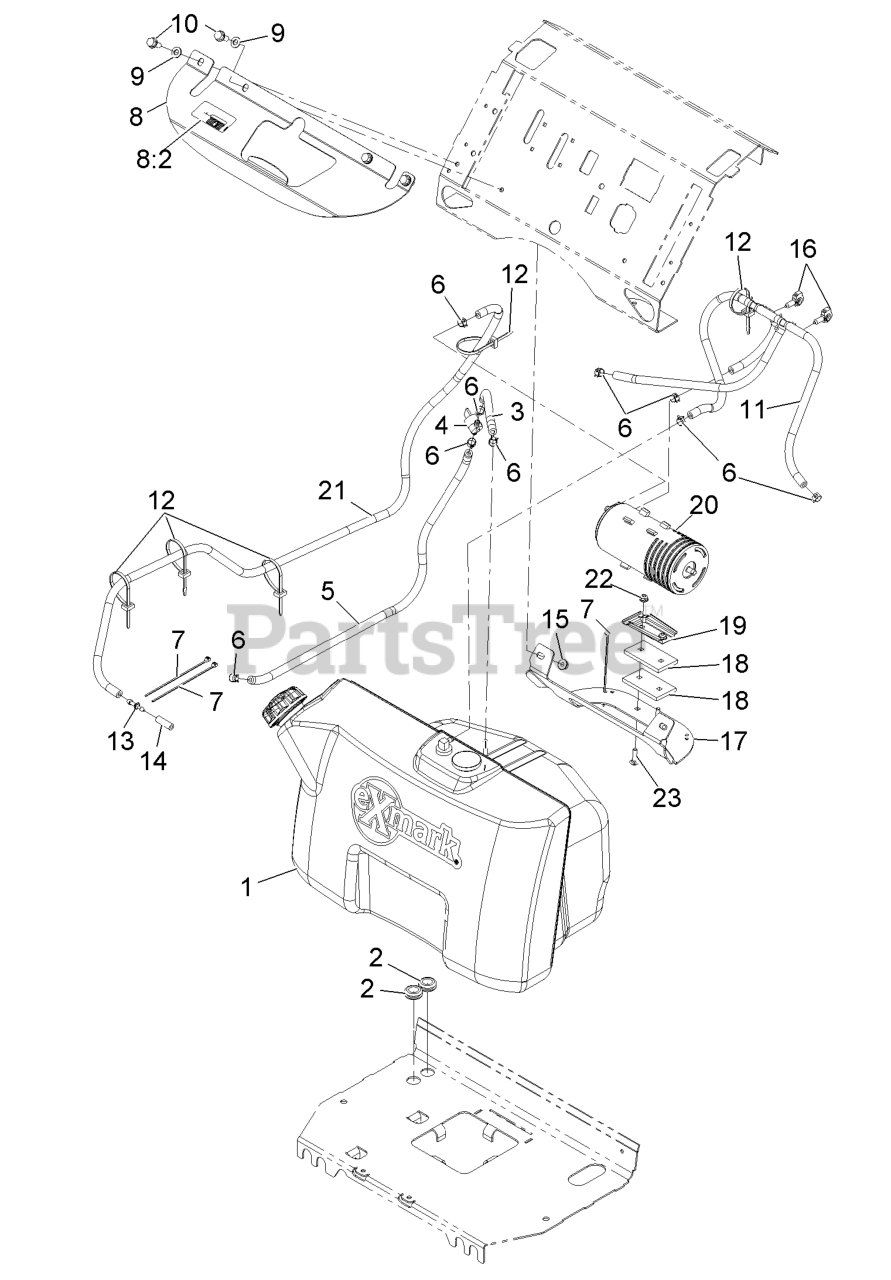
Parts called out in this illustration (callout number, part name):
2	GROMMET
3	HOSE-FUEL
4	VALVE-FUEL
5	HOSE-FUEL
6	CLAMP-HOSE
7	TIE-CABLE
8	BRACKET-TANK
8:2	DECAL-FILL, FUEL
9	WASHER-FLAT
10	SCREW-THD ROLL, HWH
11	VENT ASM
12	TIE-CABLE
13	FITTING-STRAIGHT
14	HOSE-FUEL
15	NUT-HF, NI
16	CLIP-HARNESS
17	BRACKET,CARB CANISTER
19	BRACKET-CANISTER, CARBON
20	CANISTER-CARBON, 800CC
21	HOSE-FUEL .25 X 60.00, J3
23	SCREW-CARR
